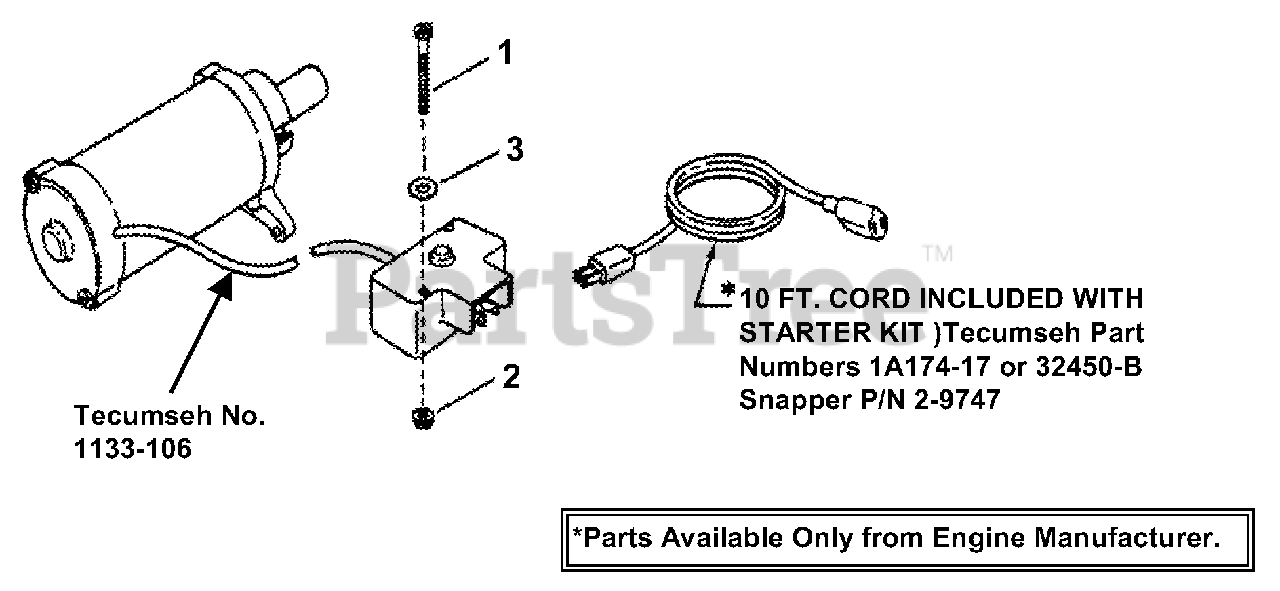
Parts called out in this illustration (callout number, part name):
1	SCREW, #10-24 x 1-3/4" Pan Head Phillips
2	NUT, #10-24 Hex Flange Lock
3	WASHER, #10 Flat
